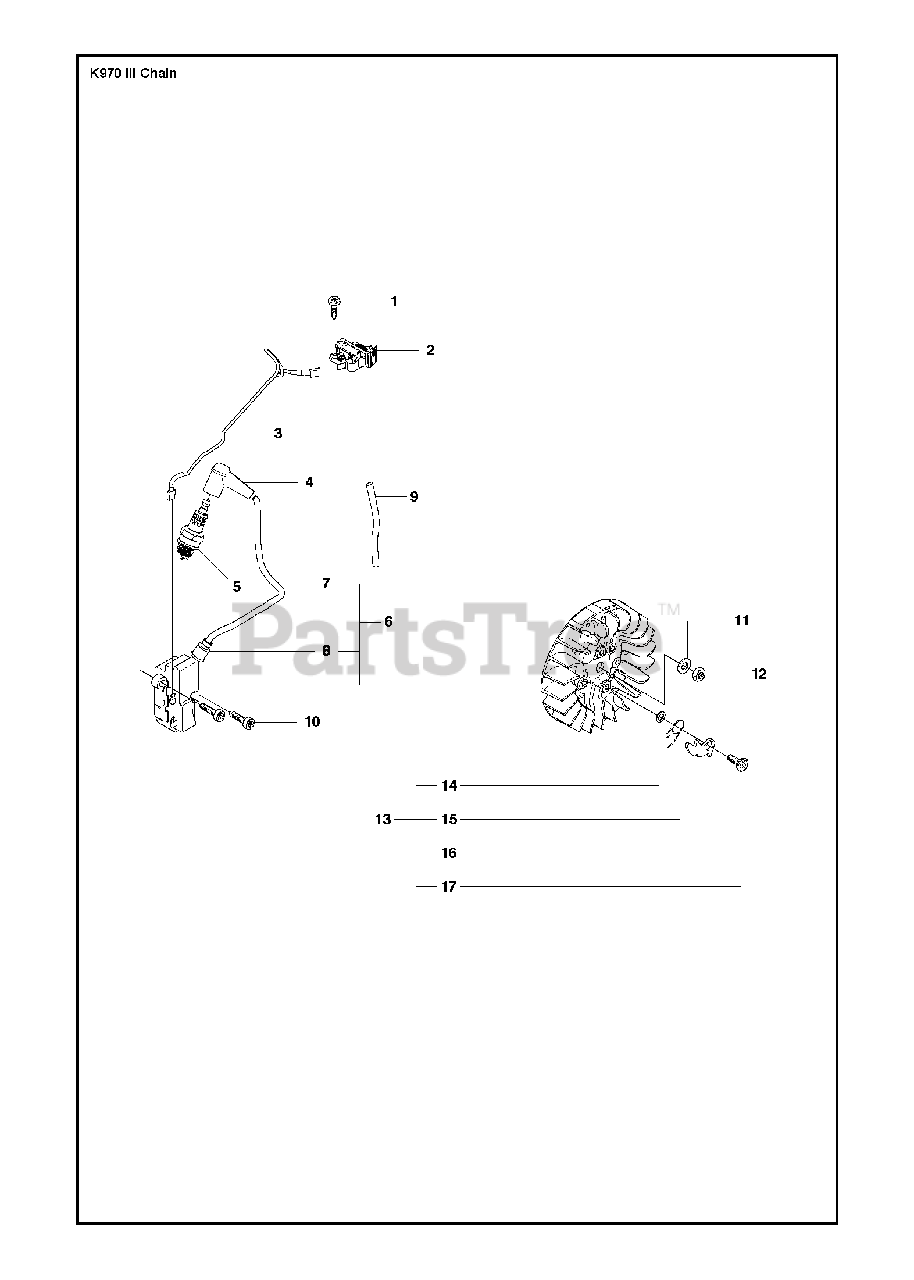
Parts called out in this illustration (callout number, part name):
2	STOP SWITCH
4	SPARK PLUG CAP
5	SPARK PLUGRCJ 6Y
6	IGNITION MODULEIncl. 7 - 8
7	IGNITION CABLE
10	SCREW ITXSCM
13	FLYWHEEL ASSYIncl. 14 - 17
17	SCREW
